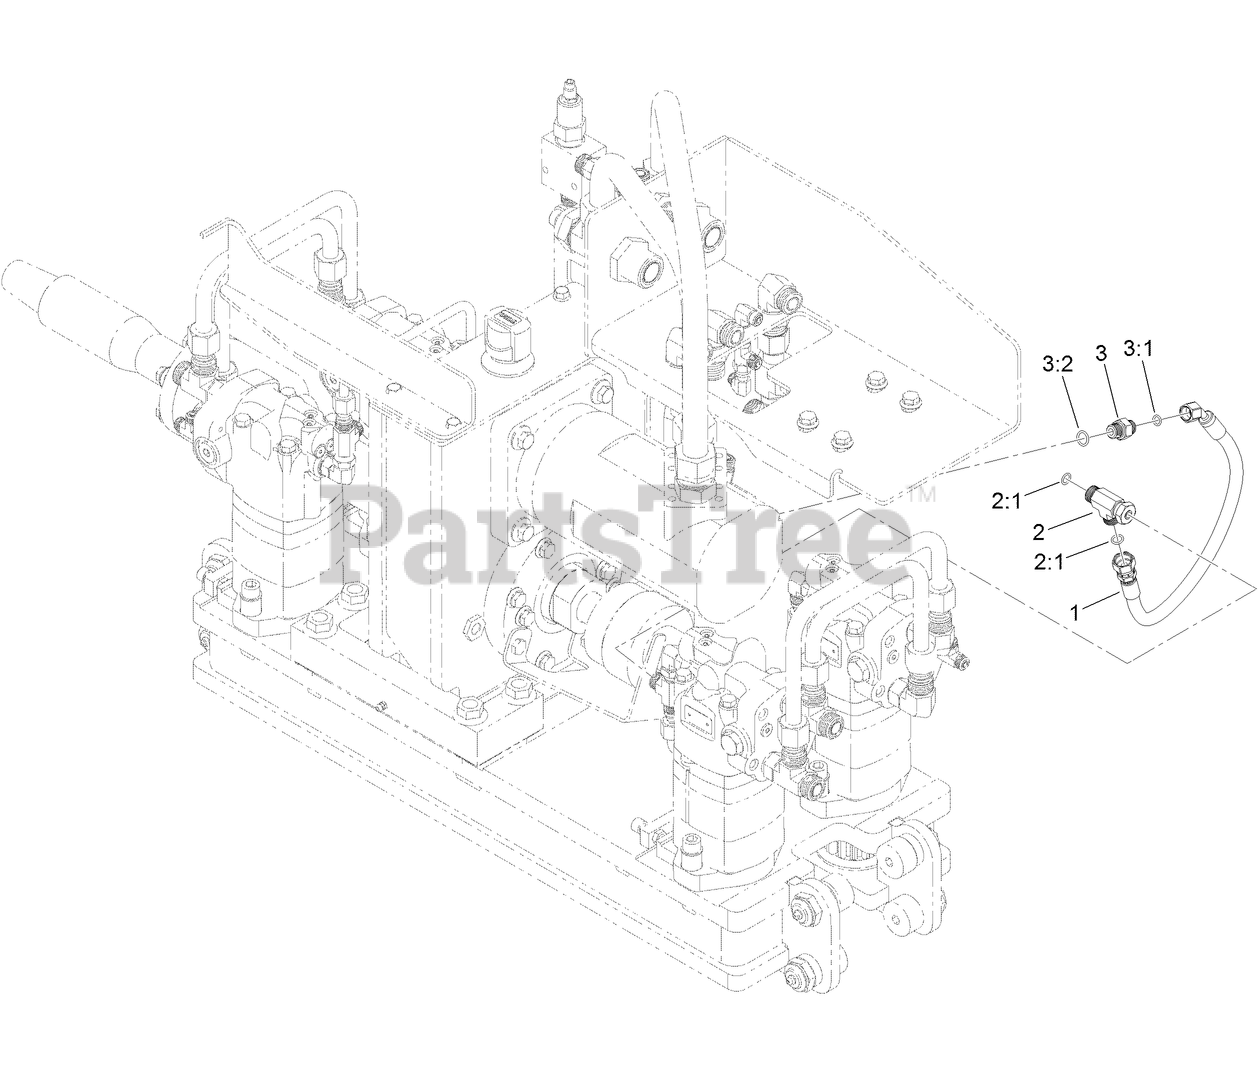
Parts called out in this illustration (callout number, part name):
1	HOSE-HYD
2	FITTING-TEE, SWIVEL NUT
2:1	O-RING
3	FITTING-STRAIGHT
3:1	O-RING
3:2	O-RING
